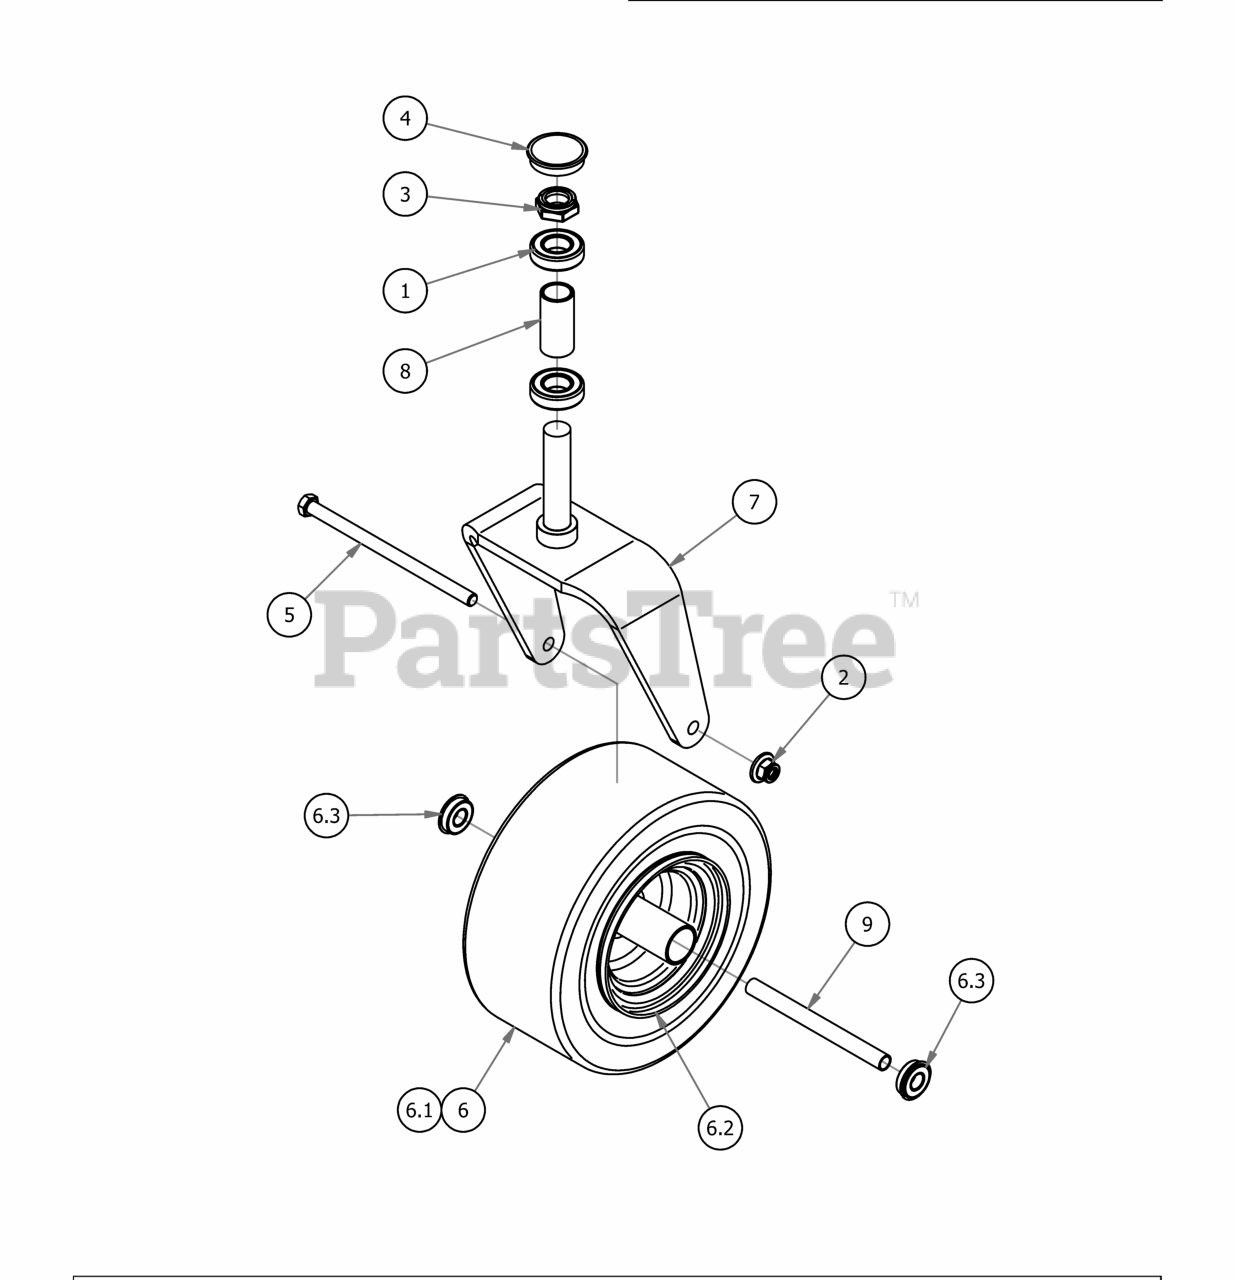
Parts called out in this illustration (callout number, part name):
1	Caster Bearing 2016 - 1641 Bearing
2	1/2-13 Nylon Flange Nut
3	1" Fine Thread 1/2 Nylock Nut
4	2017 Bearing Cover
5	1/2" x 9" GR 5 Hex Bolt
6	Tire and Wheel Assembly
6.1	13 x 6.50 - 6 Tire
6.2	Front Tire Rim
6.3	BEARING WITH RETAINER
7	Front Fork
8	2016 Front Bearing Spacer
9	Front Wheel Spanner
